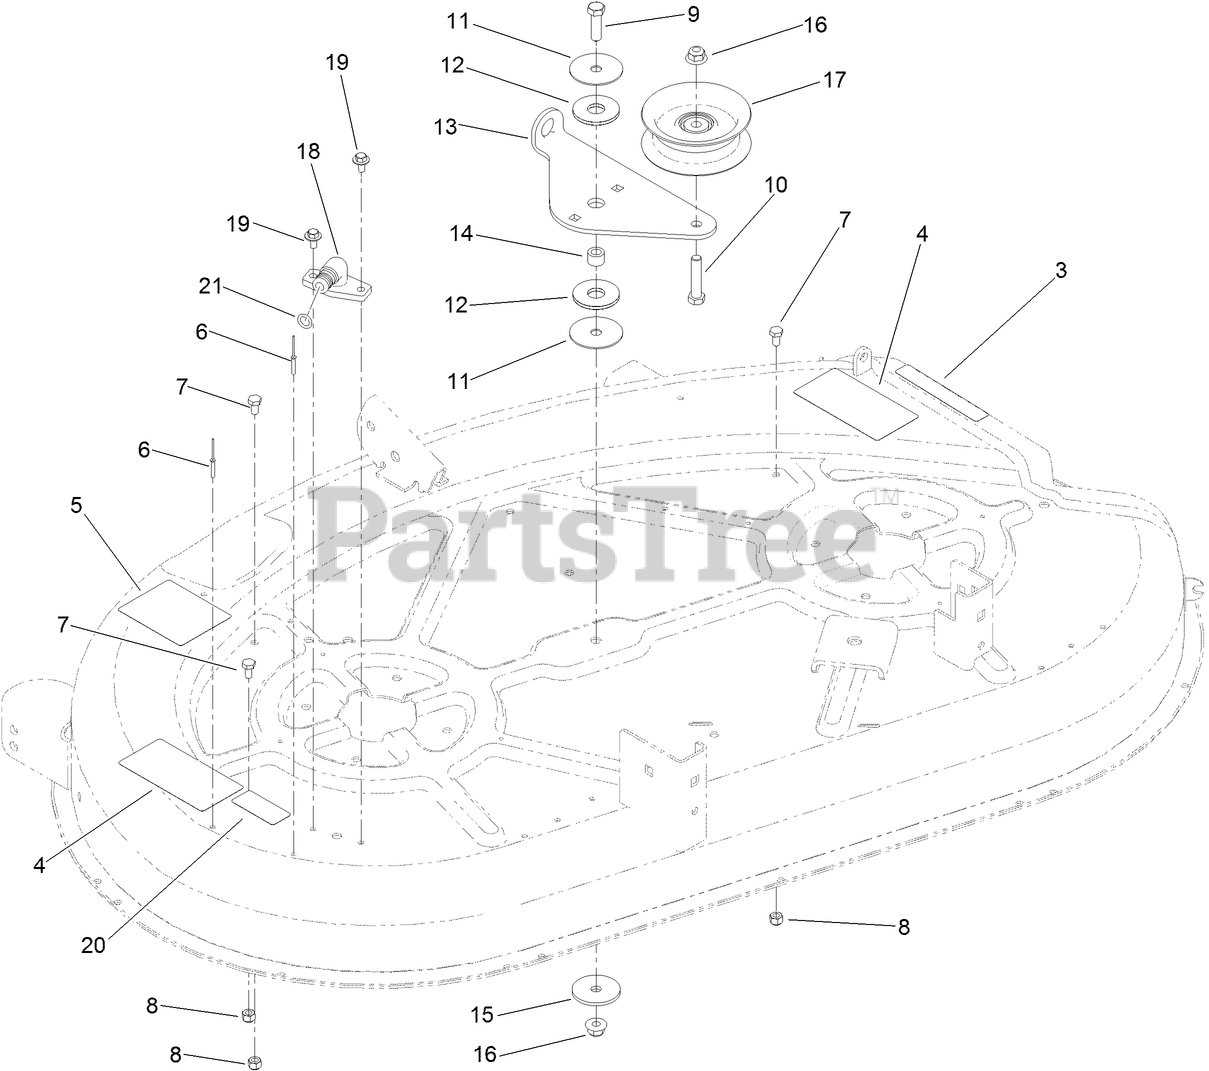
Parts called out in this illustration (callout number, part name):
3	DECAL-DANGER
4	DECAL-DANGER, DECK
5	DECAL-ROUTING, BELT
6	RIVET-BLIND
7	SCREW-HH
8	NUT-LOCK, NI
9	SCREW-HH
10	SCREW-HH
11	WASHER
12	WASHER-FRICTION, COMPOSITE
13	ARM-IDLER
14	SPACER
15	WASHER-REBOUND
16	NUT-HF, NI
17	PULLEY-IDLER, FLAT
18	FITTING-WASHOUT
19	SCREW-HHFTF
20	SERVICE DECAL
21	O-RING
